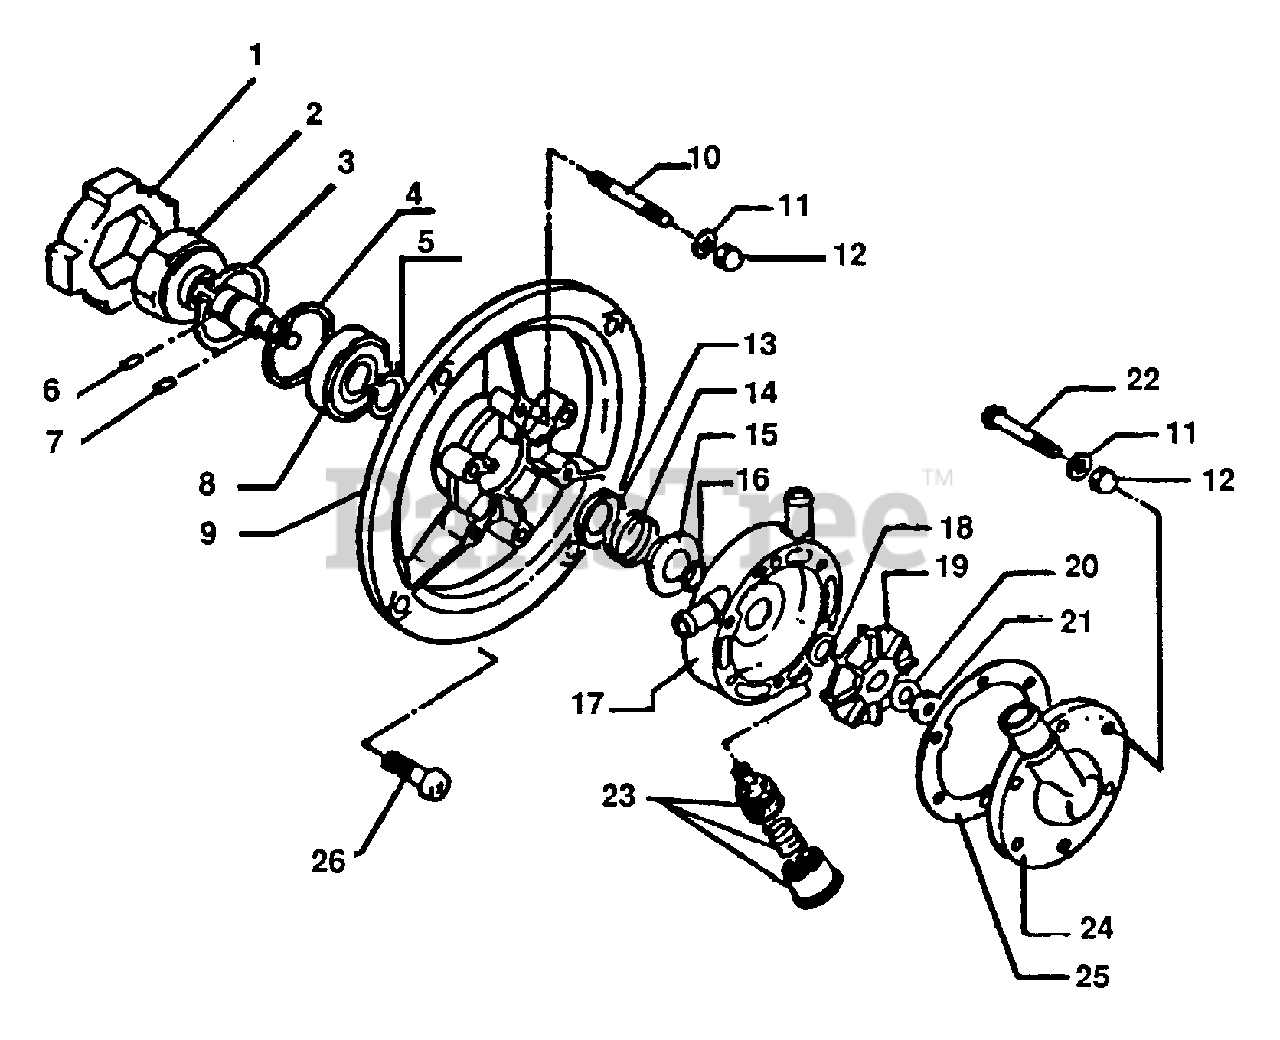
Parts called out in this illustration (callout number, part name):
1	CONNECTOR
2	SHAFT, PUMP
3	RING, RETAINING - 30
4	RING, RETAINING - 32
5	RING, RETAINING - 12
6	PIN
7	PIN
8	BEARING, BALL - 6201
9	BASE, PURGE
10	STUD
11	WASHER - 4
12	NUT - 4 - CAP
13	SEAT, SPRING
14	SPRING
15	SEAL, OIL
16	O-RING - 9
17	BODY, PUMP
18	WASHER
19	IMPELLER
20	WASHER - 6
21	NUT - 6
22	SCREW - 4X38
23	GREASE CUP ASSY
24	LID
25	GASKET, PUMP
26	SCREW - 6X15
